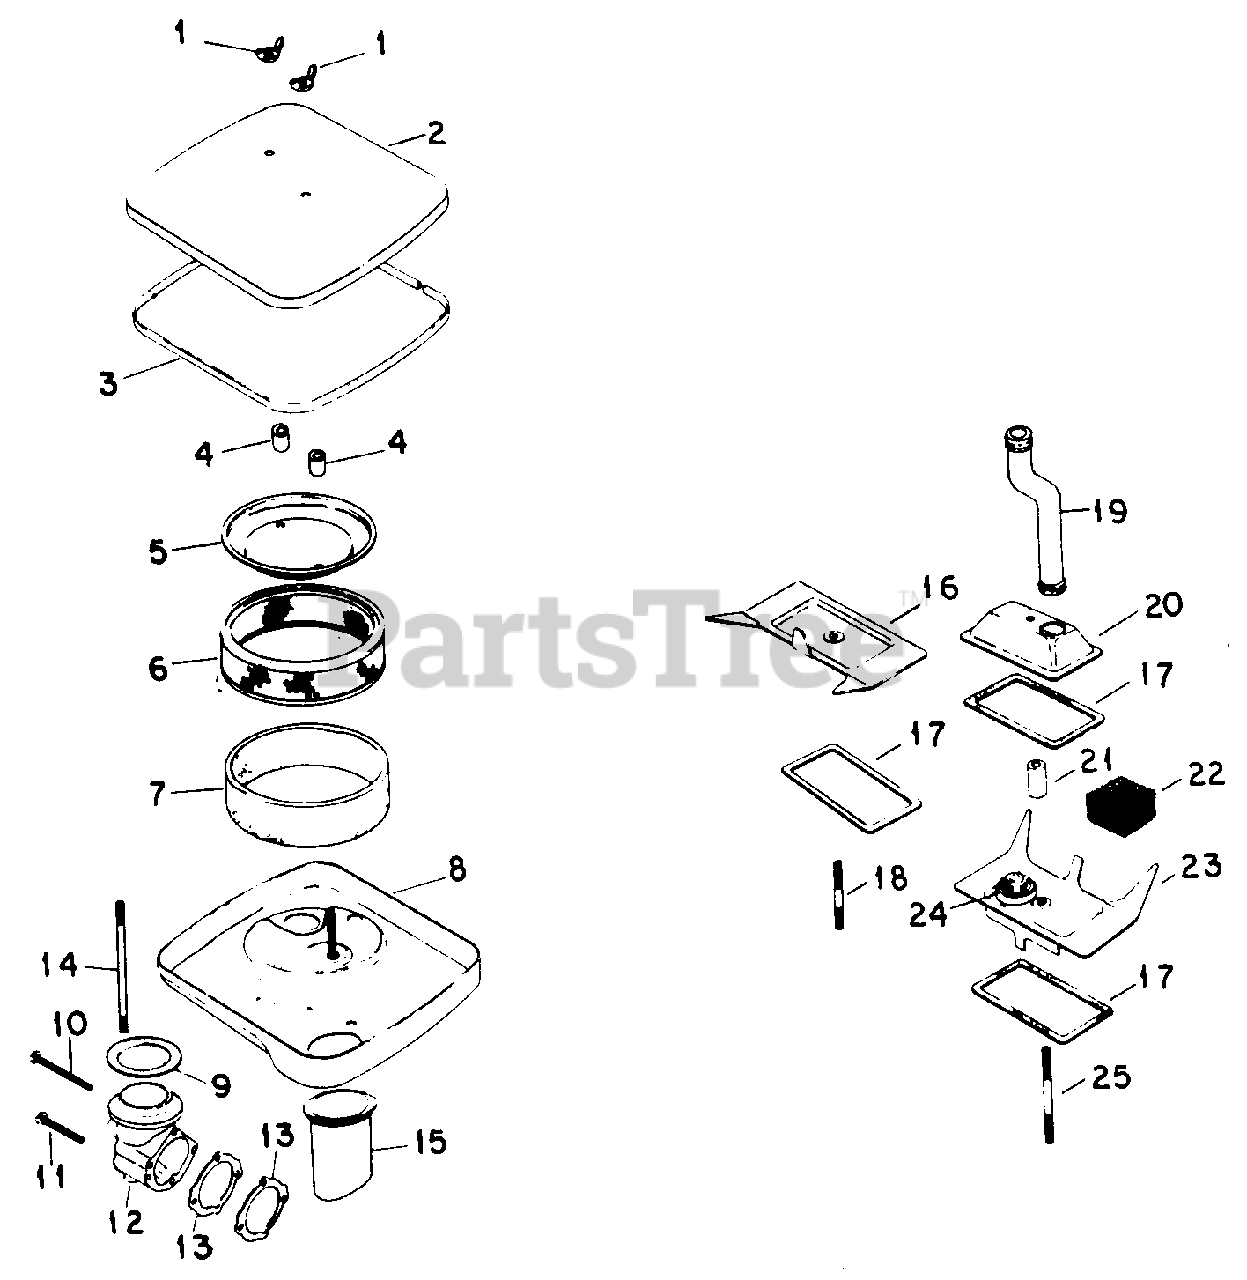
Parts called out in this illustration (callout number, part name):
1	Nut, Wing, 1/4-20
2	Cover, Air Cleaner
3	Seal, Air Cleaner Cover
5	Cover, Air Cleaner Element
6	Element, Air Cleaner
7	Element, Precleaner
8	Base, Air Cleaner
9	Gasket, Air Cleaner Base
10	Screw, 10-32 X 2-1/4 Slt Pn Hd
11	Screw, 10-32 X 1-1/2 Slt Pn Hd
12	Elbow, Air Cleaner
13	Gasket, Elbow
15	Tube, Air Intake
16	Cover, Valve
17	Gasket, Cover
19	Hose, Breather
20	Cover, Valve
21	Seal, Breather
22	Filter, Breather
23	Kit, Breather
24	Valve, Umbrella
